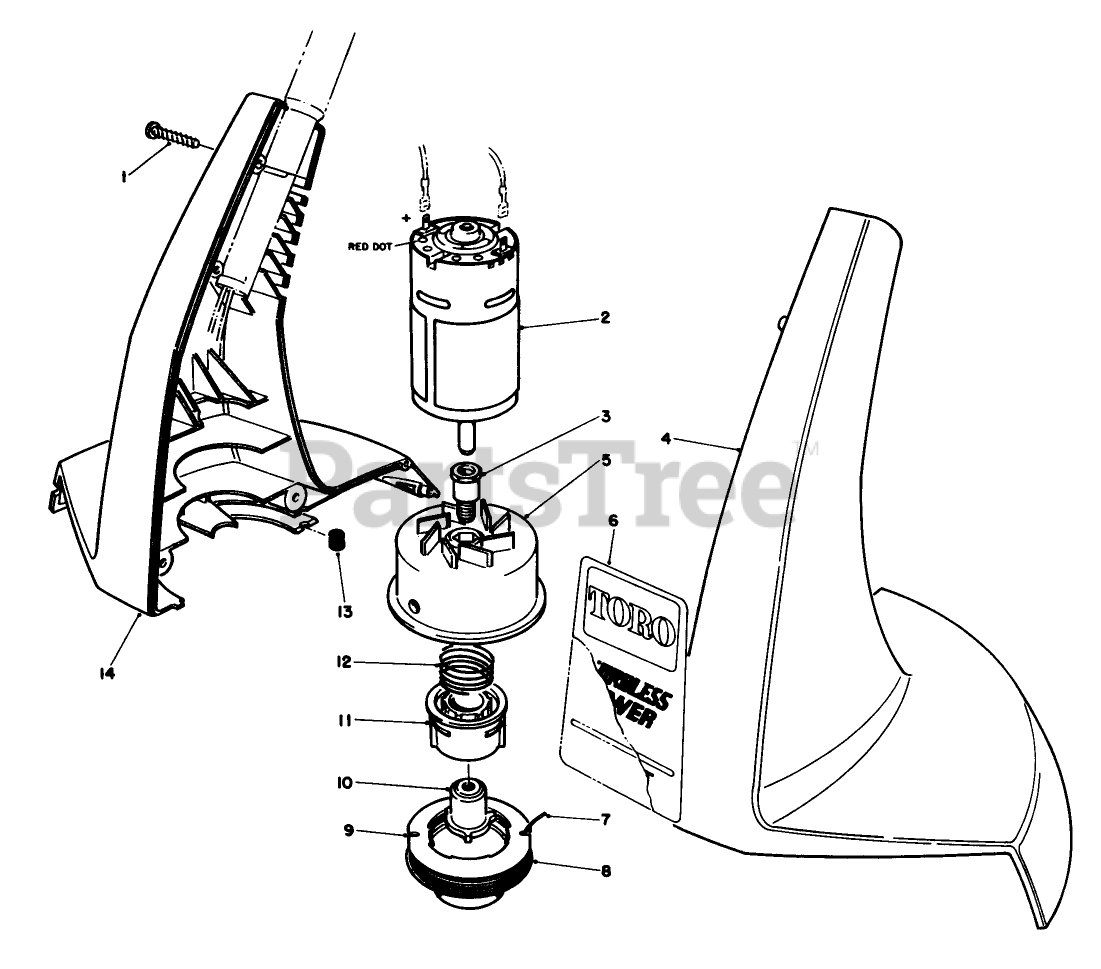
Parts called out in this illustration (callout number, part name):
1	Screw
2	Motor Assembly (Incl. Ref. #3)
3	Extension-Shaft
4	LH HOUSING, 12V TRIMMER
5	Drum-Assembly
6	DECAL-TRIMMER
8	Pre-wound Spool (Incl. Ref. #7 & 9)
9	CAP-SPOOL
10	DRIVER
11	CORE - SPOOL
12	Spring
13	GROMMET
14	RIGHT HAND HOUSING ASM
